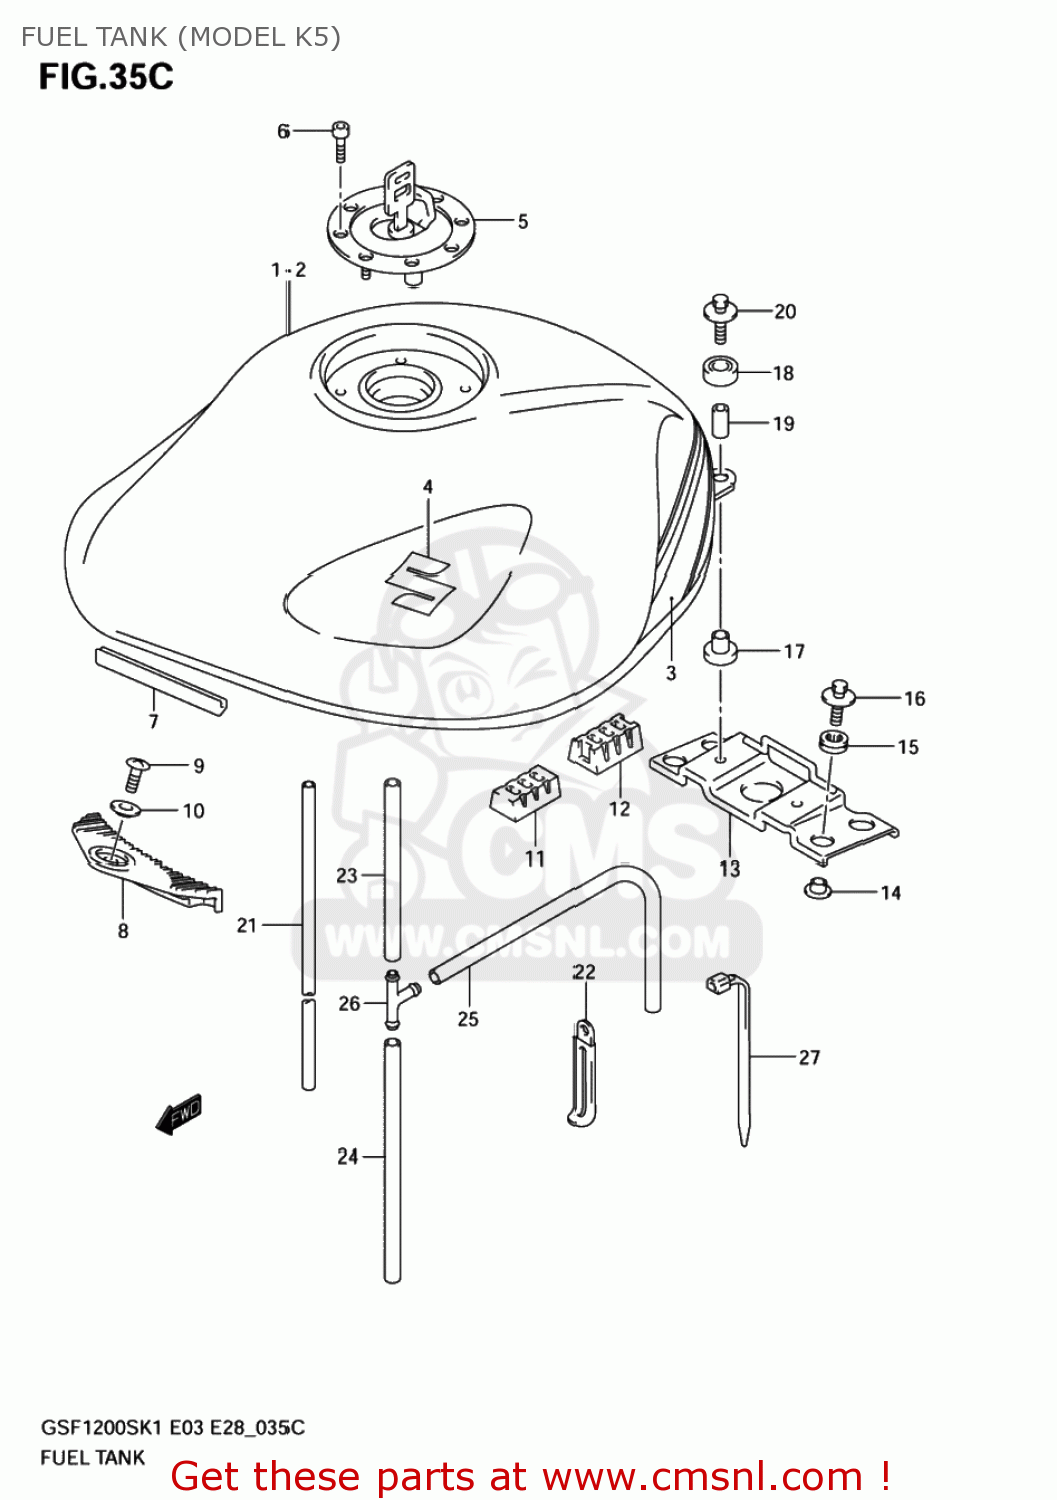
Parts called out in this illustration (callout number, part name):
1	TANK ASSY,FUEL(BLACK)
2	TANK ASSY,FUEL
3	TAPE SET,FUEL TANK
4	EMBLEM,S
5	CAP SET,FUEL TANK
6	BOLT(5X20)
7	MOLDING
8	CUSHION,FUEL TANK FR
9	SCREW
10	WASHER
11	CUSHION,SUPPORT(50X25X32)
12	CUSHION,TANK SIDE
13	BRACKET,FUEL TANK RR
14	WASHER
15	CUSHION
16	BOLT(6X25)
17	CUSHION
18	CUSHION,FUEL TANK RR
19	SPACER(6.5X9X18)
20	BOLT(6X30)
21	HOSE(7X11X2000)
22	CLAMP(L:97)
23	HOSE(5X8.2X600)
24	HOSE(5X8.2X600)
25	HOSE(5X8.2X600)
26	JOINT,3 WAY
27	CLAMP(L:125)
